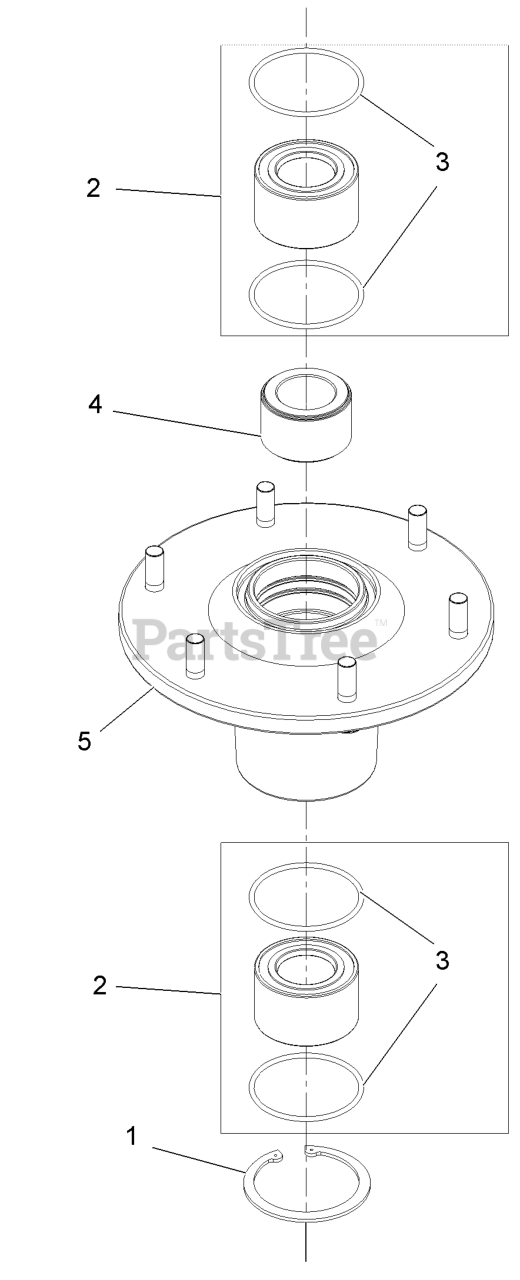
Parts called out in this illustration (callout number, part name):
1	Ring-Retaining
2	Asm, Bearing W/O-Rings
4	Spacer, Bearing
5	Asm, Housing W/Studs
